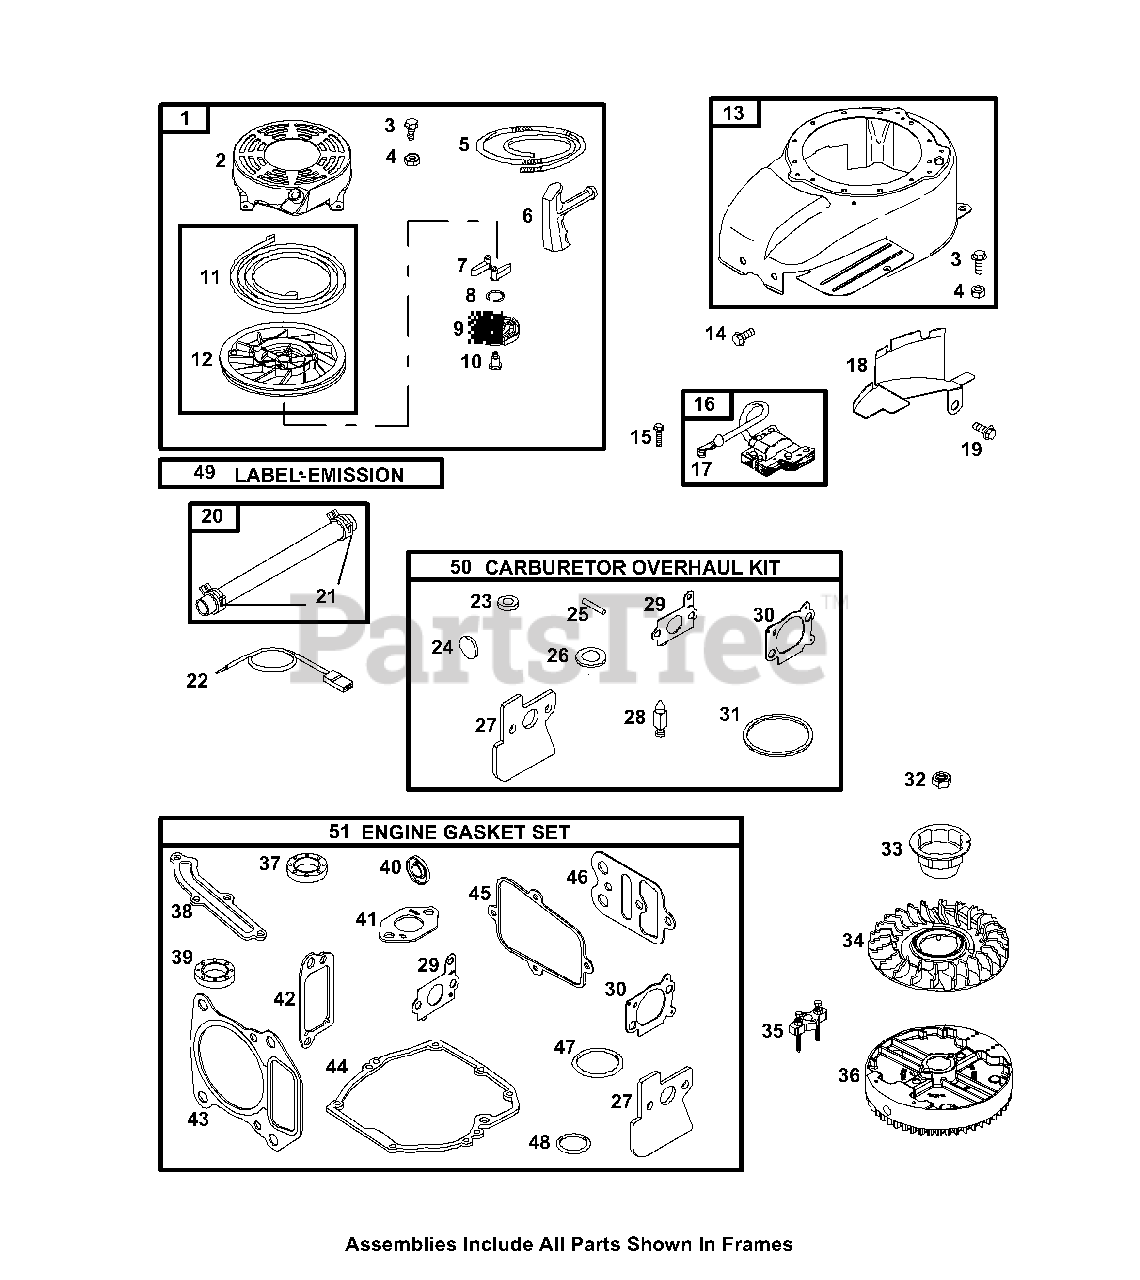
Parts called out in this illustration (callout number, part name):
1	Starter-Rewind
2	Housing Rewind-Starter
3	Screw (Rewind Starter)
4	Nut (Rewind Starter)
5	Rope-Starter (Cut to Required Lgth.)
6	Grip-Starter Rope
7	Ratchet-Pawl
8	Spring-Friction
9	Plate-Pawl Friction
10	Screw (Pawl Friction Plate)
11	Pulley/Spring Assembly (Spring)
12	Pulley/Spring Assembly (Pulley)
13	Housing-Blower
14	Screw (Blower Housing)
15	Screw (Magneto Armature)
16	Armature-Magneto
17	Terminal-Sparkplug
18	Guard-Flywheel
19	Screw (Flywheel Guard)
20	Line-Fuel (Cut to Required Length)
21	Clamp-Hose
23	Seal-Throttle Shaft
24	Plug-Welch
25	Pin-Float Hinge
26	Washer-Sealing
27	Spacer-Carburetor
28	Kit-Needle/Seat
29	Gasket-Intake
30	Gasket-Air Cleaner
31	Gasket-Float Bowl
32	Nut (Flywheel)
33	Cup-Flywheel
34	Fan-Flywheel
35	Flywheel Puller
36	Flywheel
37	Seal-Oil (PTO Side)
38	Gasket-Breather Passage
39	Oil Seal (Magneto Side)
40	Seal-Valve
41	Gasket-Exhaust
42	Gasket-Breather
43	Gasket-Cylinder Head
44	Gasket-Crankcase
45	Gasket-Rocker Cover
46	Gasket-Cylinder Head Plate
47	Seal-O RIng (Dipstick)
48	Seal-O Ring (Dipstick Tube)
49	Label-Emission
50	Kit-Carburetor Overhaul
51	Gasket Set-Engine
